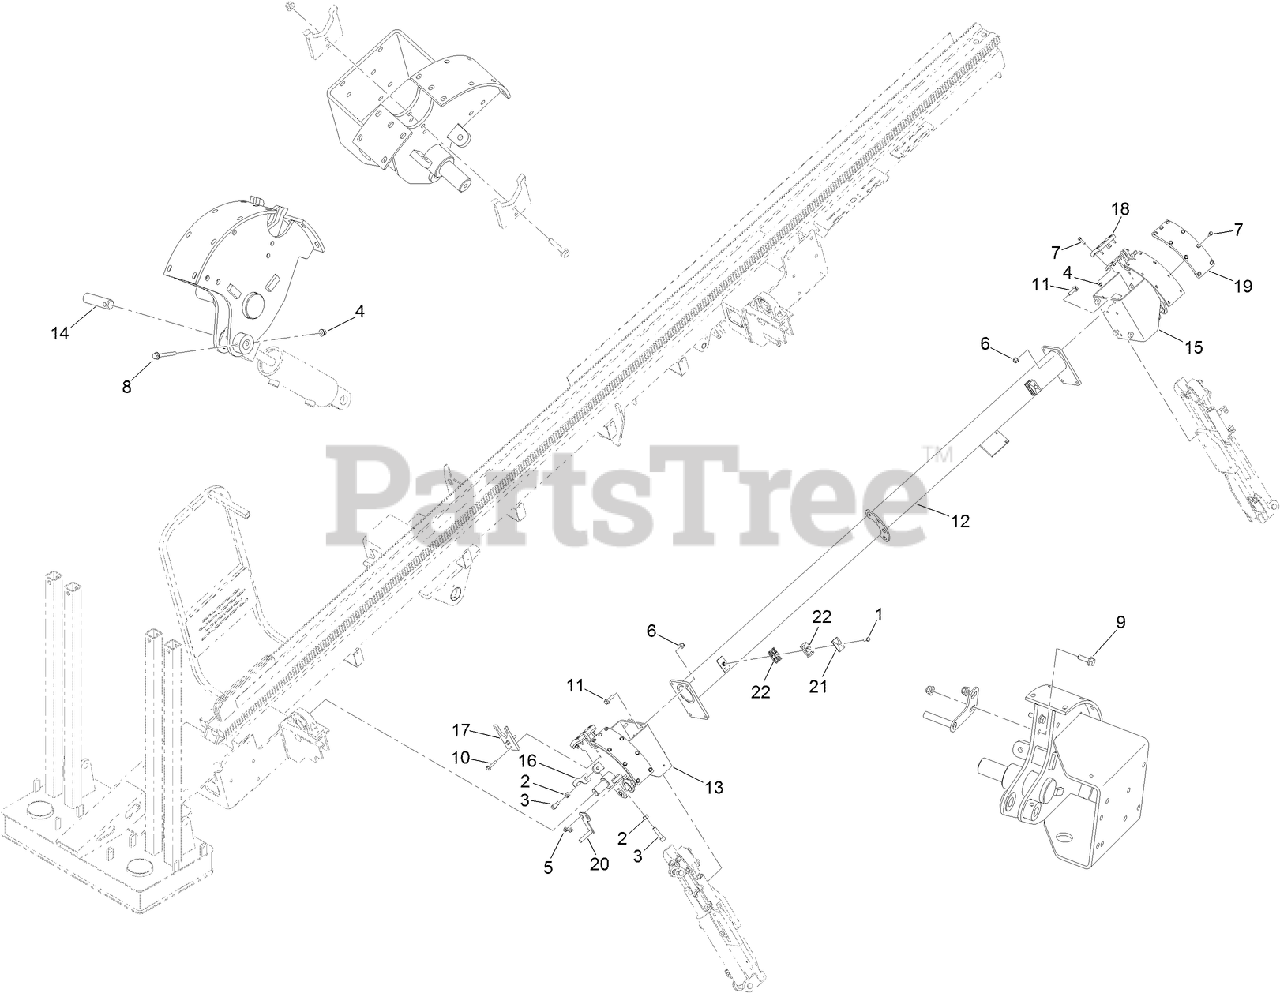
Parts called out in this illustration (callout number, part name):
1	SCREW-HH
3	SCREW-HSFH
4	NUT-FLANGE, NI
5	NUT-LOCK, HHF
6	NUT-LOCK, NI
7	SCREW-HHF
8	SCREW-HHF
9	SCREW-HHF
10	SCREW-HHF
11	SCREW-HHF
12	SPINE-LOADER, ROD
13	LOWER CAM ASM
14	PIN-STRAIGHT
15	UPPER CAM ASM
16	PLATE-POINTER
17	PLATE-GUIDE, PIPE
18	PAD-WEAR, ROD LOADER
19	PAD-WEAR, ROD LOADER
20	FLAG-SENSOR
21	PLATE-COVER, TWIN
22	CLAMP-HALF (SET OF 2)
